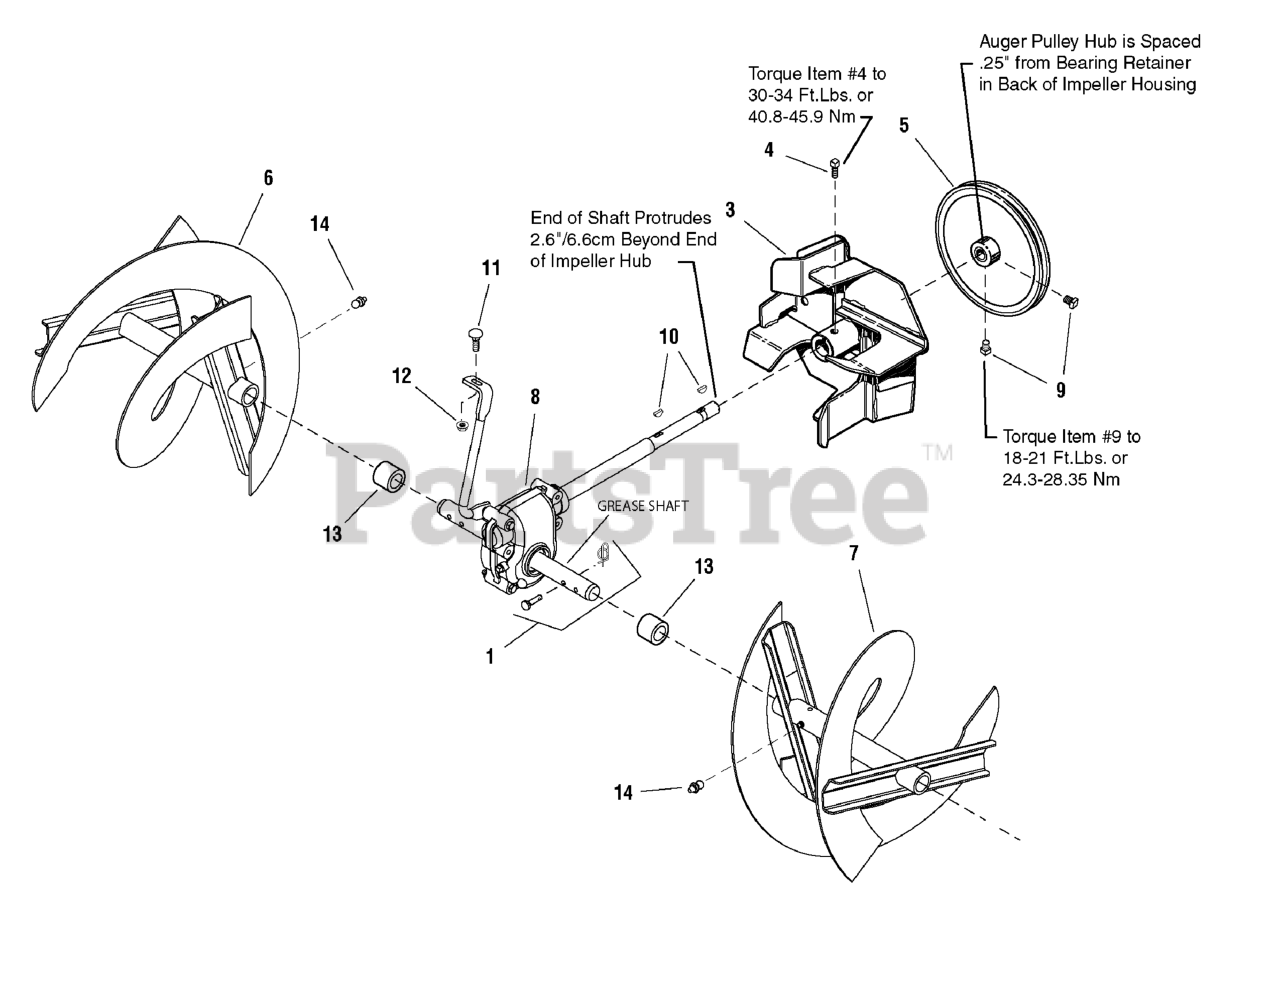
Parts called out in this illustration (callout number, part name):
1	KIT, Shear Pin
3	IMPELLER ASSEMBLY
4	SCREW, Set Square Head Cup Point, 3/8-16 x 1/2 G8
5	PULLEY, 8.40 OD .752ID .720WD W/Hub
6	AUGER ASSEMBLY, 28" & 30" R.H.
7	AUGER ASSEMBLY, 28" & 30" L.H.
8	GEAR BOX ASSEMBLY
9	SCREW, Set Square Head Cup Point, 5/16-18 x 1/2 G8
10	KEY, Woodruff
11	CARRIAGE BOLT, 5/16-18 x 3/4 G5
12	NUT, Hex Flange Whiz Lock, 5/16-18
13	TUBE, Plastic
14	FITTING, Lube, 1/4 Drive, No Check Ball
